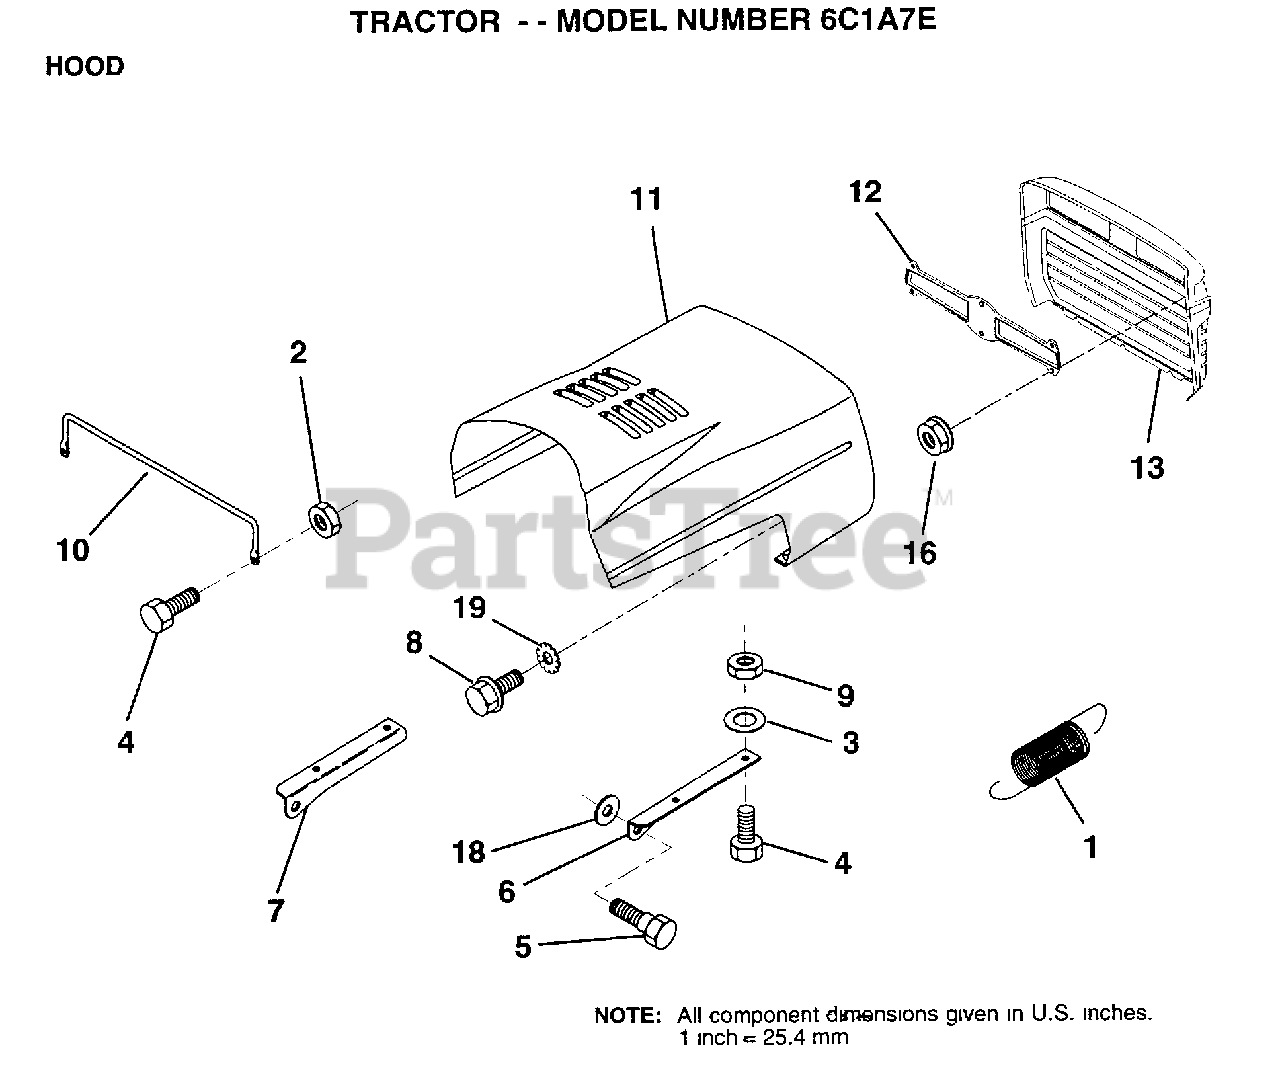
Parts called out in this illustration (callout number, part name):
1	EXT SPRING
2	NUT HXKEP 1/4X20
3	WASHER
5	BOLT.SHLD.5/16-18
6	BRKT HOOD RH
7	BRKT HOOD LH
8	SCREW SLTD HXHD
9	NUT
10	"BRACE,HOOD"
11	HOOD
13	GRILL (BLACK)
16	NUT
18	WASHER
19	LOCKWASHER GT
